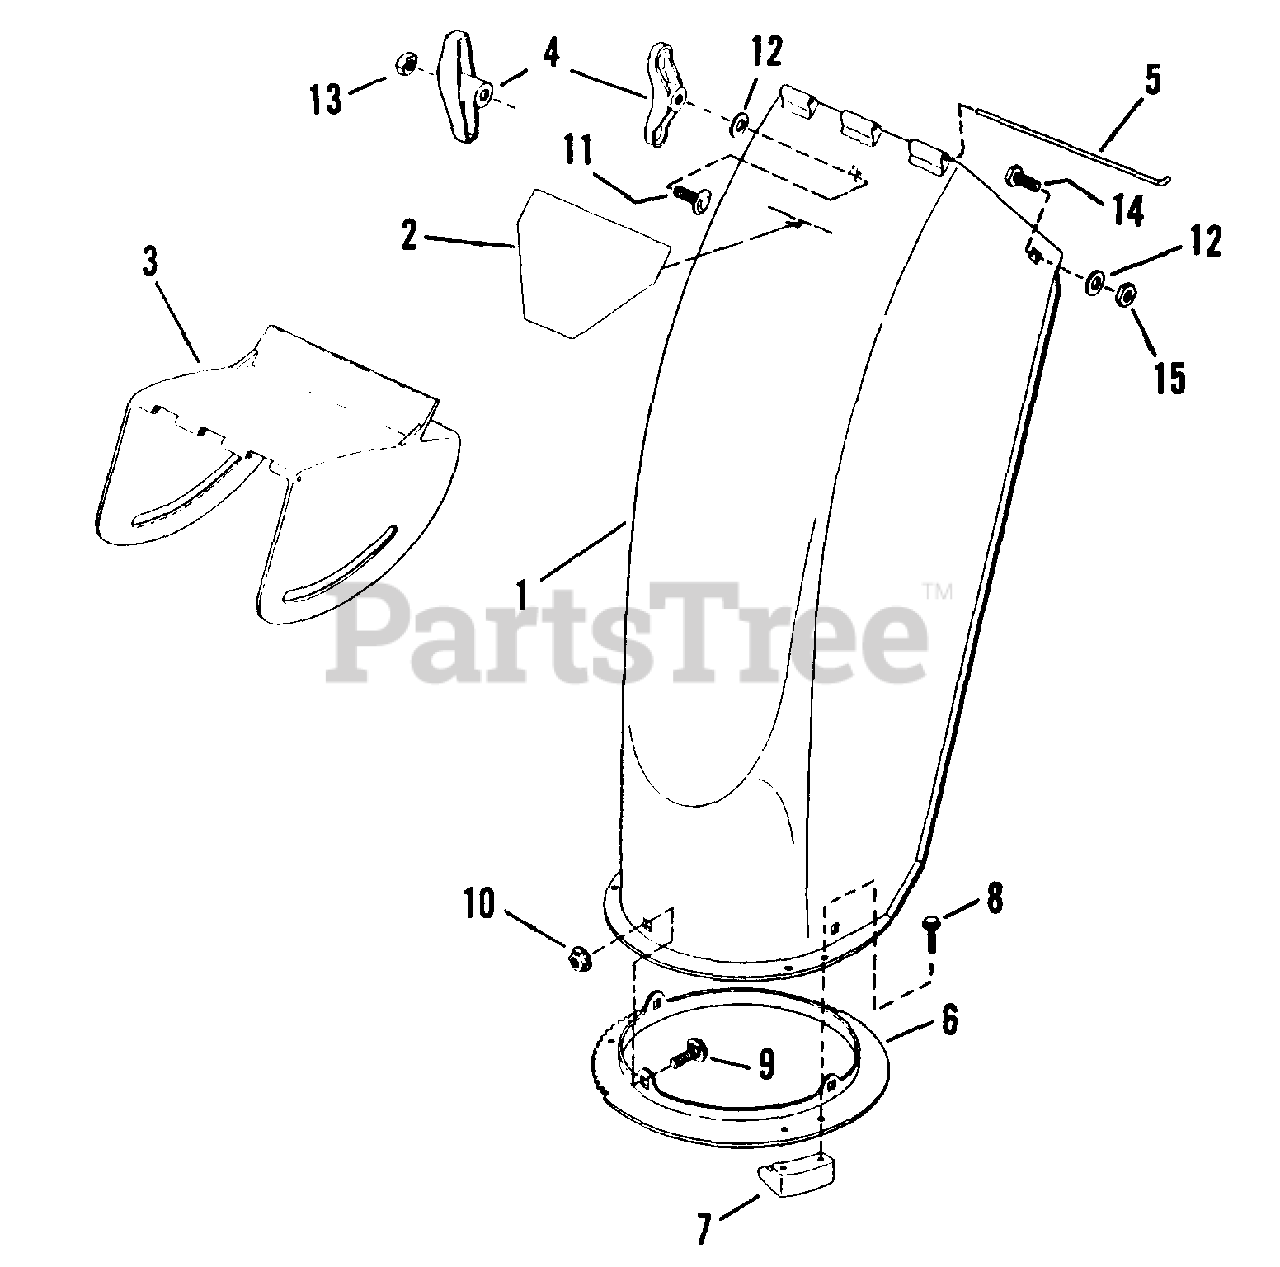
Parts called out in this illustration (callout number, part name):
1	ASSEMBLY, Discharge Chute
2	DECAL, Hand Danger
3	DEFLECTOR, Discharge Chute
4	NUT, 5/16 - 18 Wing (Series 0 & 1)
5	PIN, Hinge
6	RING, Chute
7	RETAINER (Chute Ring to Collector Housing)
8	SCREW, #10 - 24 x 5/8 Self-Tapping
9	BOLT, 5/16 - 18 x 5/8 Carriage
10	NUT, 5/16 - 18 Hex Flange Lock
11	BOLT, 5/16 - 18 x 3/4 Carriage
12	WASHER, 5/16 Flat
13	NUT, 5/16 - 18 Hex
14	SCREW, 5/16 - 24 x 3/4 Hex Head Cap
15	NUT, 5/16 - 24 Hex Center Lock
